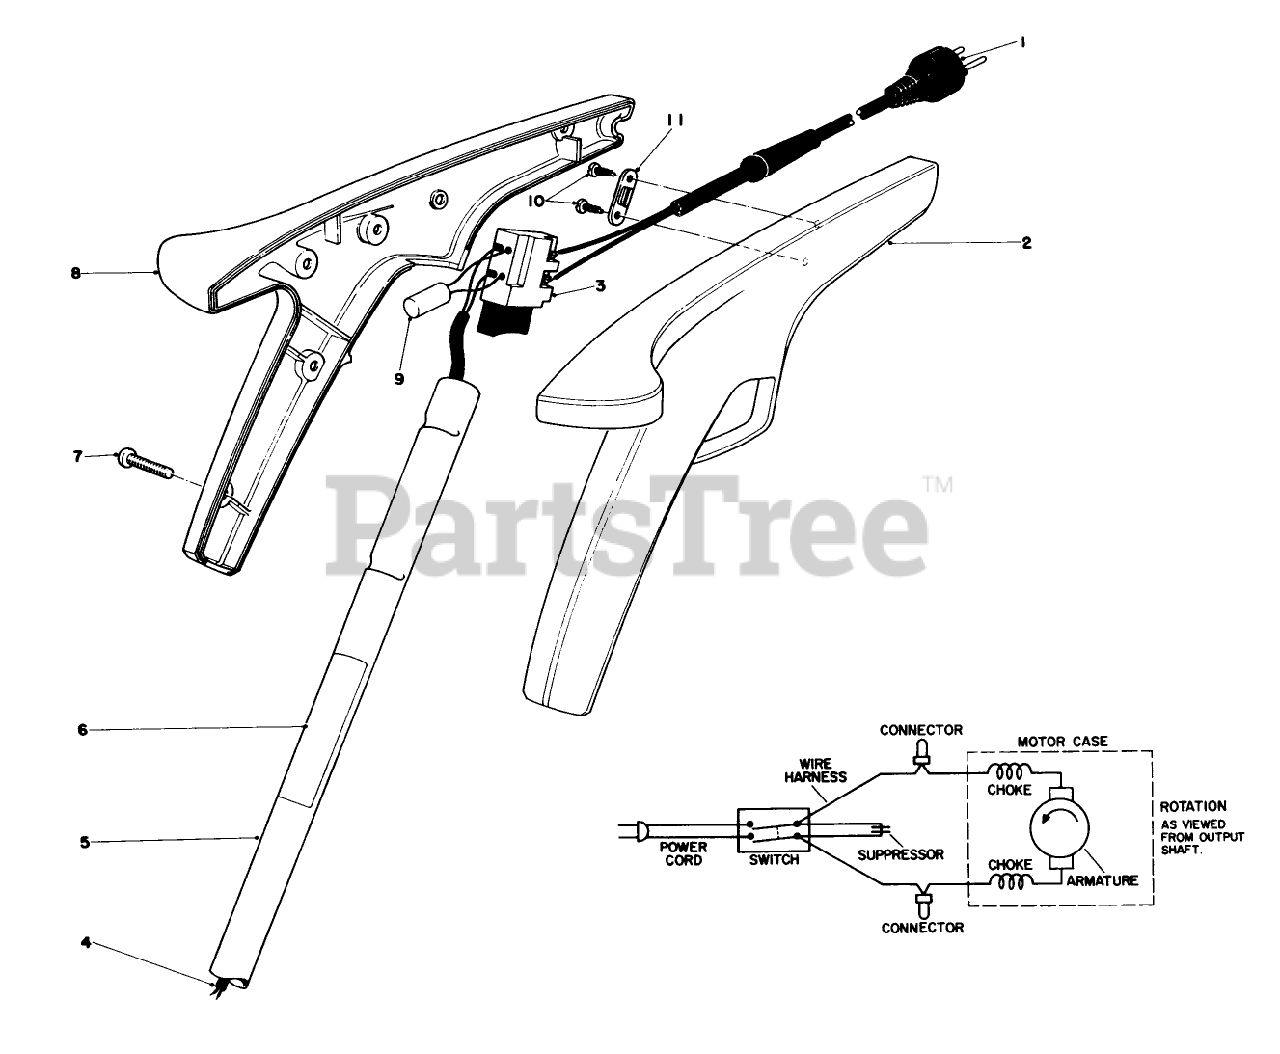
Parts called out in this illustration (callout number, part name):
1	Power Cord
2	Left Hand Grip
3	Switch
4	Wiring Harness
5	Handle Tube
6	Decal-Caution
7	Screw
8	Right Hand Grip
9	Suppressor
10	SCREW-PPH
11	Clamp
